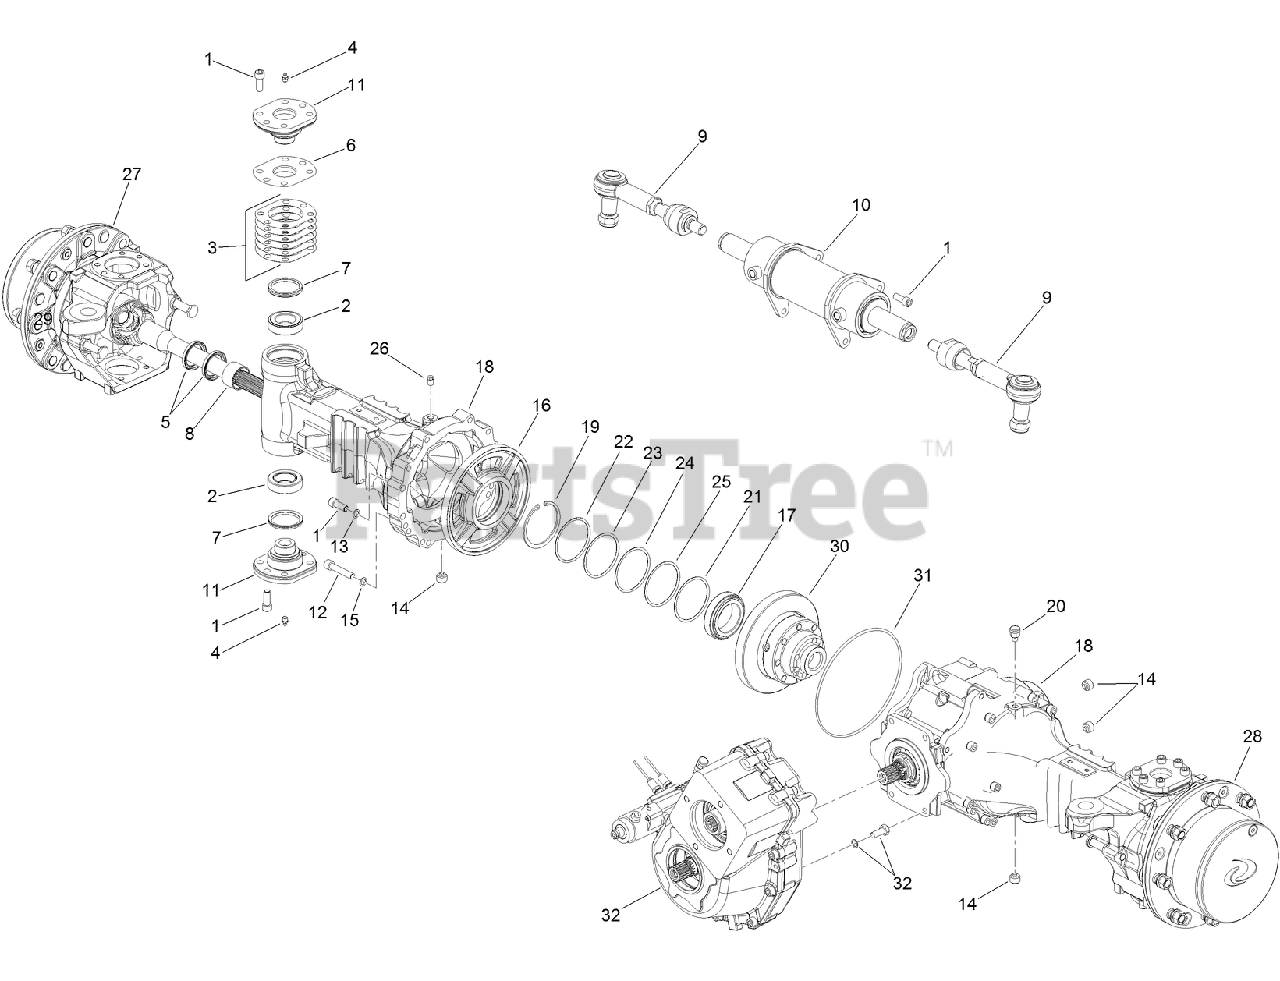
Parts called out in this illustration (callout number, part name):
1	SCREW-SOC HD
2	JOINT-BALL
3	SHIM-JOINT, ARTICULATED (0.2)
4	GREASER
5	SEAL-OIL
6	SHIM-JOINT, ARTICULATED (0.1)
7	V-RING
8	BUSHING
9	ROD-TIE
10	CYLINDER-STEERING
11	PIN-FLANGED
13	WASHER-COPPER
14	PLUG-MAGNETIC
15	WASHER-SCHNORR
16	FLANGE-DIFFERENTIAL
17	BEARING
18	HOUSING-SIDE
19	RING-SNAP
20	PLUG-BREATHER
21	SHIM (1.0)
22	SHIM (0.2)
23	SHIM (0.3)
24	SHIM (0.35)
25	SHIM (0.5)
27	O-RING
28	WHEEL HUB GROUP
29	WHEEL HUB GROUP
30	PINION GROUP
31	DIFFERENTIAL GROUP
32	GEARBOX GROUP
